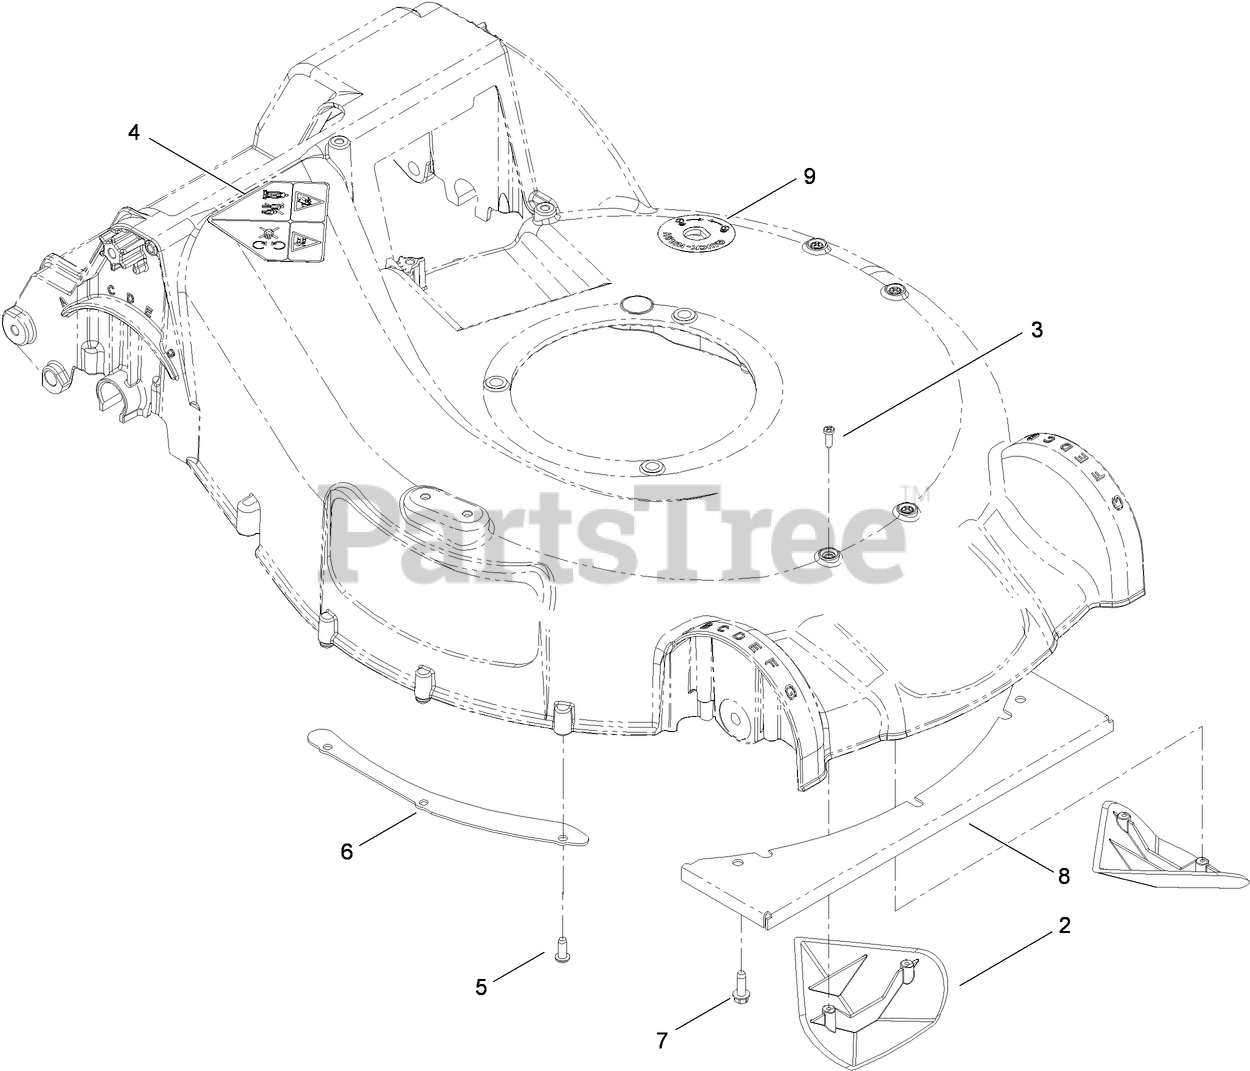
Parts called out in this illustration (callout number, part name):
2	KICKER-HOUSING
3	SCREW-PPH
4	DECAL-DANGER
5	SCREW
6	SHEET-LIP
7	SCREW-HWHTF
8	PLATE-COVER, FRONT
9	DECAL-PORT, WASHOUT
